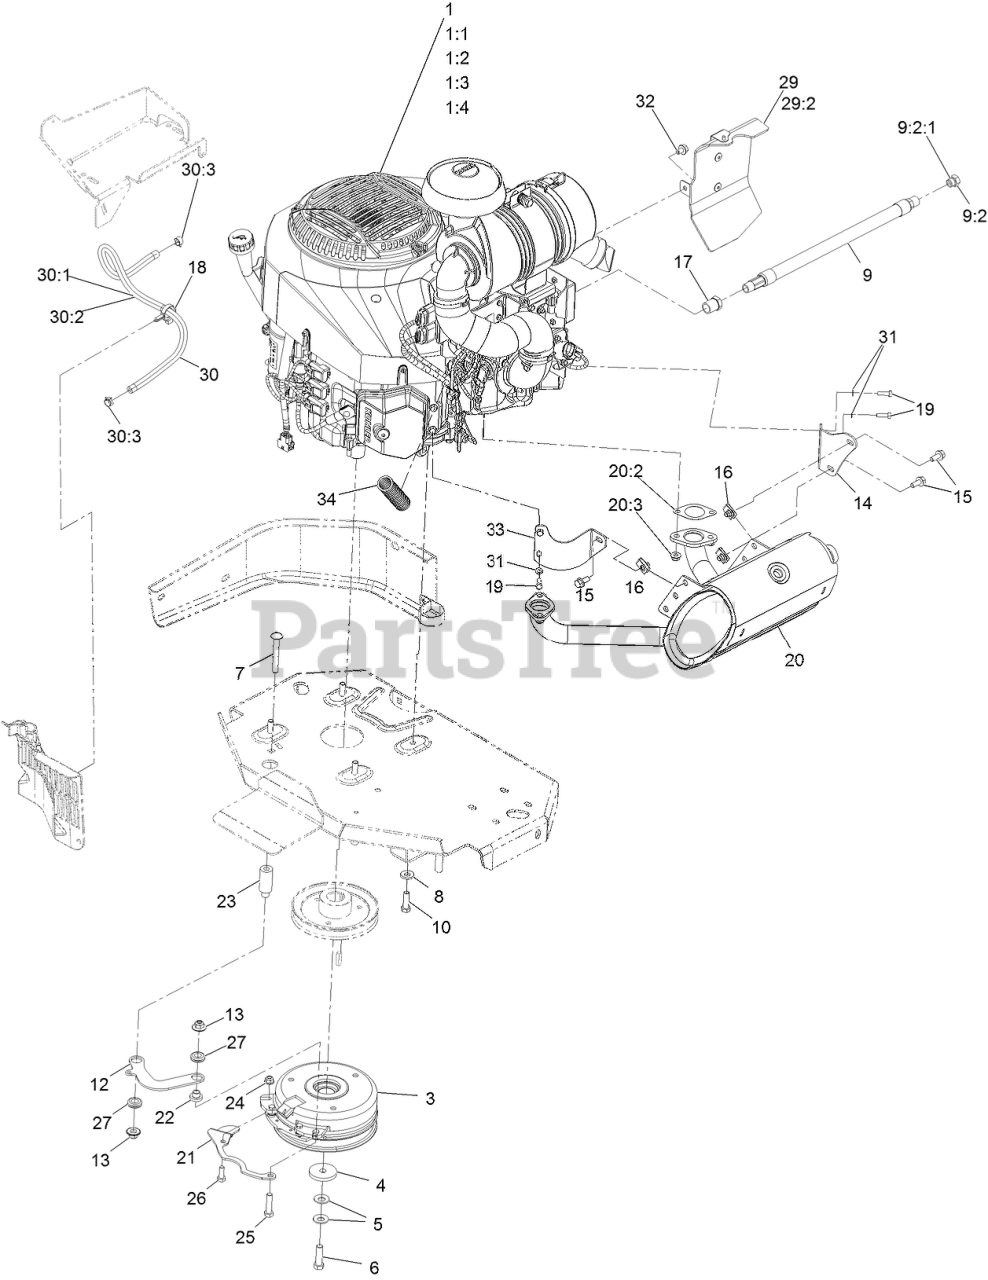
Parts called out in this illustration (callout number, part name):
1:1	Kohler 52 050 02-S Engine Oil Filter
1:2	Kohler 25 083 01-S Engine Air Filter
1:3	Kohler 25 083 04-S Safety Filter
1:4	Kohler 25 050 42-S Fuel Filter
3	CLUTCH KIT
4	WASHER-CLUTCH
5	WASHER-SPRING
6	SCREW-HH 7/16-20 X 1 1/2 W/LOCTITE
7	SCREW-CARR
8	WASHER-BELLEVILLE
9	OIL DRAIN HOSE ASM
9:2	PLUG-HH
9:2:1	O-RING
10	SCREW-HH
12	LINK-ANCHOR, CLUTCH
13	Nut-Nyloc 3/8-16 Flg
14	BRACKET-MUFFLER
15	SCREW-HHF
17	BUSHING
18	CLAMP-HOSE
19	SCREW-HH M6-1 X 20Mm W/Patch
20	MUFFLER KIT
20:2	GASKET-EXHAUST
20:3	NUT-FLANGE, LOCK
21	BELT-GUIDE
24	NUT-HF, NI
25	SCREW-HH
26	SCREW-HH
27	GROMMET-RUBBER
29	Baffle ASM
29	Baffle Kit
29:2	SCREW-HWH
29:2	Screw-HHF
30	FUEL LINE ASM
30:1	HOSE-FUEL
30:2	SLEEVE, THERMAL
30:3	CLAMP-HOSE
31	WASHER-SPRING
32	Screw-HHF
33	BRACKET-MUFFLER, FRONT
34	CONDUIT-CONVOLUTED
